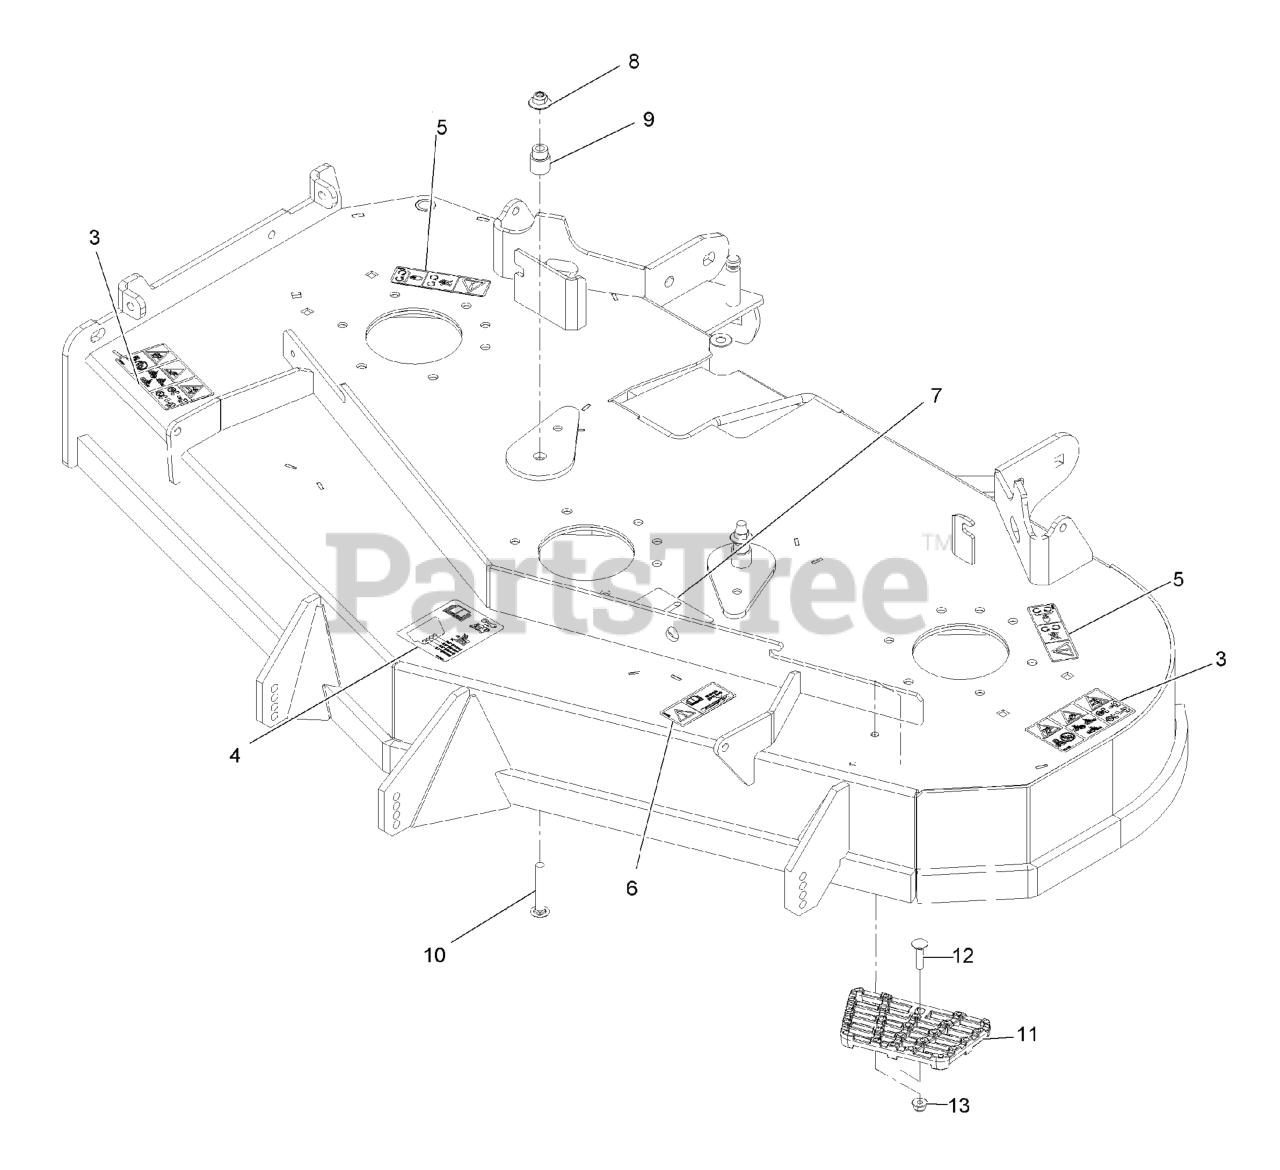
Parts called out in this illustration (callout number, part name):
3	DECAL-DANGER THROWN OBJECTS
4	DECAL-ROLLER, ANTI-SCALP
5	DECAL-COVER, MISSING
6	DECAL-TORQUE, BOLT
7	DECAL-BELT ROUTING
8	DECK IDLER ASM
9	STEP-DECK
10	Bolt-Carriage 5/16-18 X 1 1/4
11	NUT-HF, NI
